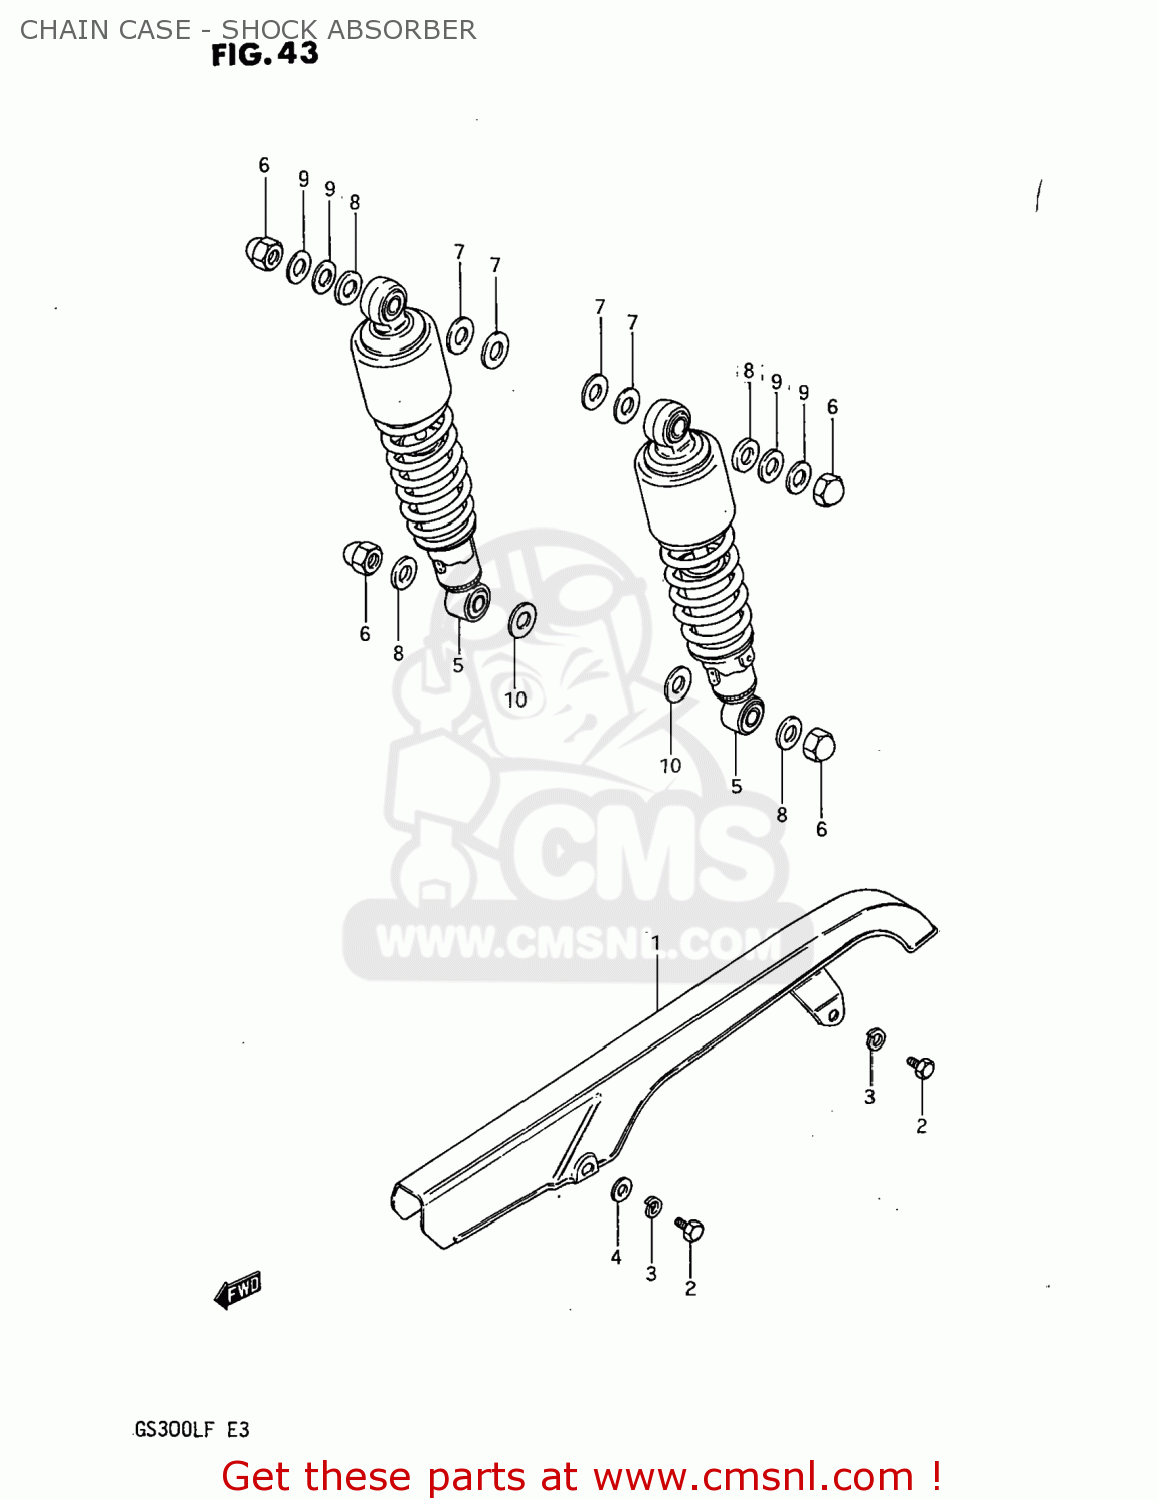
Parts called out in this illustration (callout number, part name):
1	CASE,CHAIN
2	BOLT
3	LOCK WASHER
4	WASHER
5	ABSORBER ASSEMBLY,REAR SHOCK
6	NUT, LOWER LH
7	WASHER
8	WASHER
9	WASHER(10.5X24X3.2)
10	WASHER (12.5X24X1.6)
